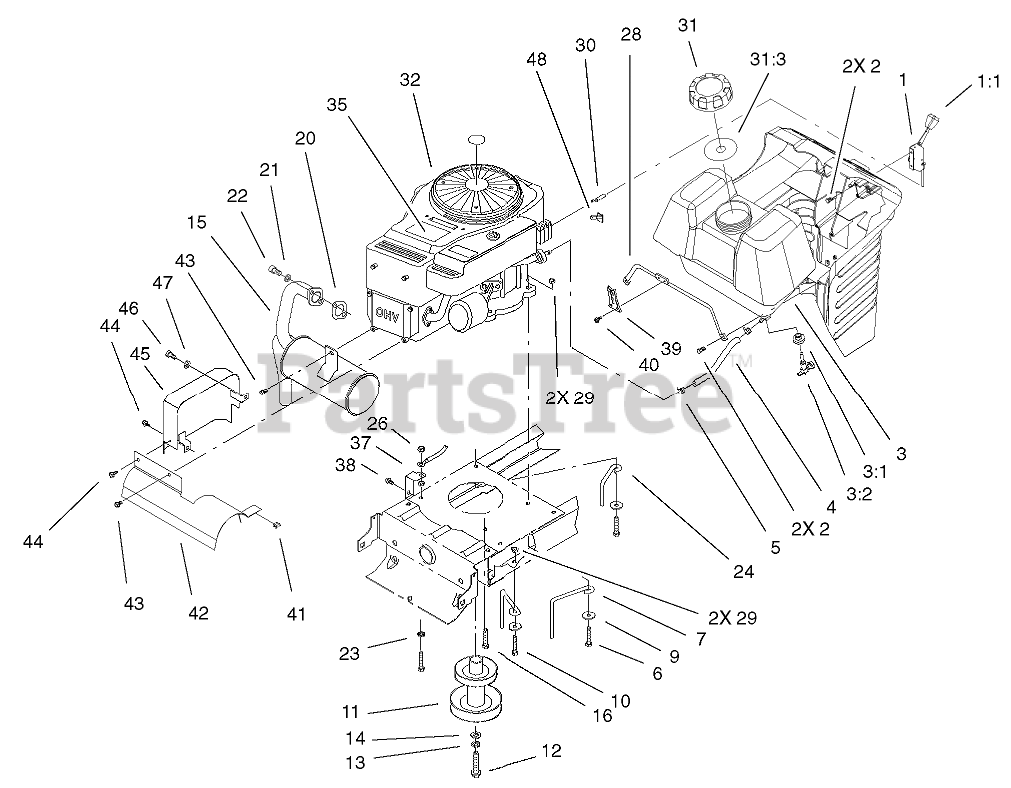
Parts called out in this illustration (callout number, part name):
1	THROTTLE CONTROL ASM
2	SCREW-SPECIAL
3	GAS TANK ASM
3:1	BUSHING
3:2	VALVE-FUEL
4	HOSE-FUEL
5	CLAMP-HOSE
6	SCREW-HH
7	GUIDE-BELT, ENGINE
9	WASHER-PIVOT
10	SCREW-HH
11	PULLEY-ENGINE ASM
12	SCREW-HH
13	WASHER-LOCK
14	WASHER-FLAT
15	MUFFLER-EXHAUST
16	SCREW-HWH, TAPTITE
20	GASKET-EXHAUST
21	WASHER-LOCK
22	SCREW-HSH
23	WASHER-LOCK
24	GUIDE-BELT, RH
26	NUT-KEPS
28	ROD-TANK, GAS
29	NUT-LOCK, NI
30	THROTTLE CABLE ASM
31	GAS CAP ASM
31:3	GASKET-CAP, GAS
35	DECAL-ENGINE
37	BRACKET-GROUND
38	SCREW-HWH
39	LATCH-HOOD
40	SCREW-HWH
41	CLIP-TINNERMAN
42	SHIELD-MUFFLER
43	SCREW-HWH
44	SCREW-HWHTF
45	HEAT SHIELD ASM
46	SCREW-HH
47	WASHER-LOCK
48	Reducer-Throttle, Rpm (only on: 71242)
